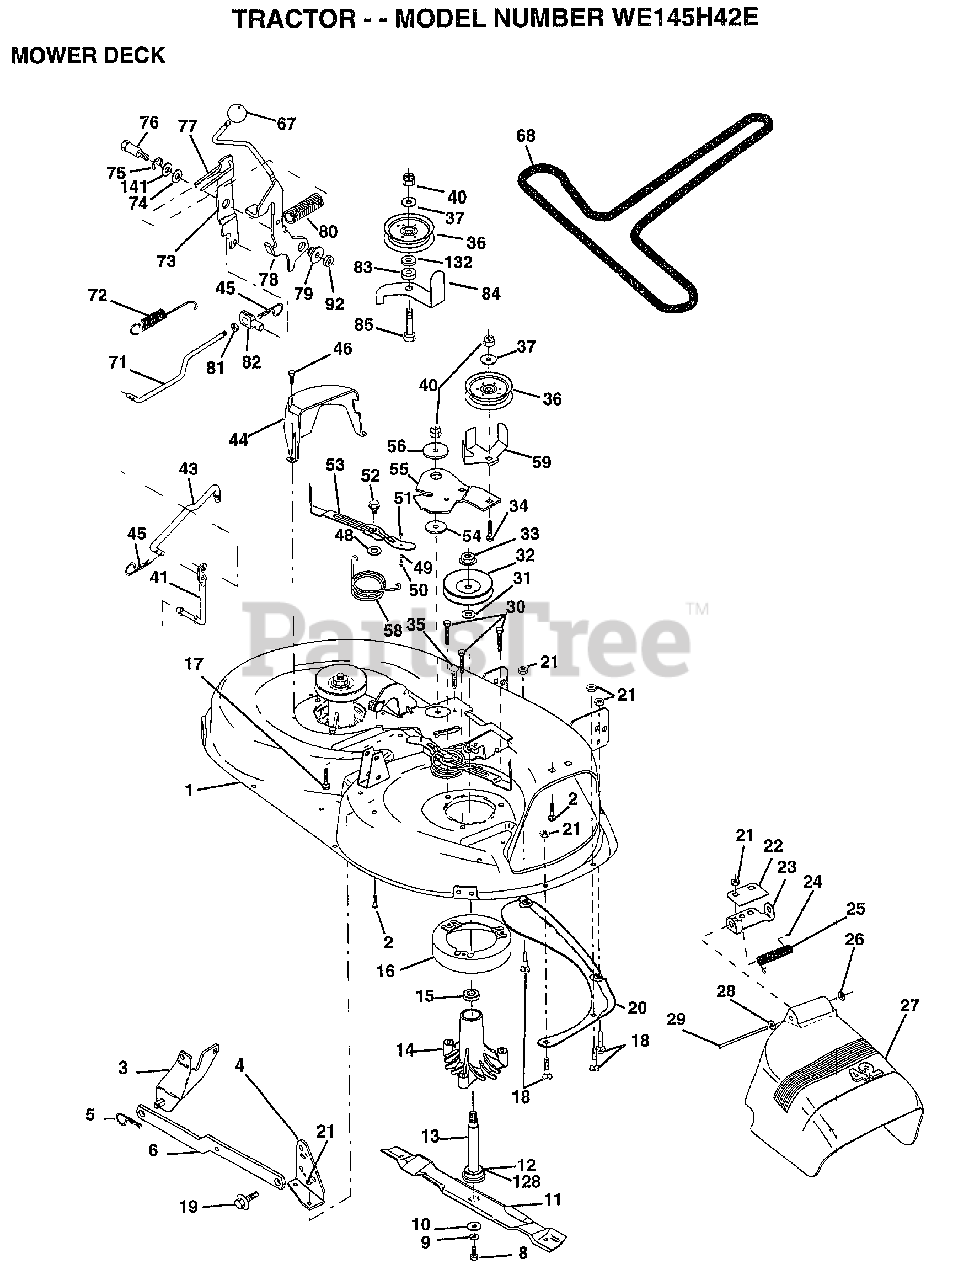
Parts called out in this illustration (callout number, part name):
1	"HOUSING ASSY.42"""
2	BOLT
3	BRKT ASM SWAY BAR
4	BRKT DECK SW BAR
8	BLADE BOLT
10	WASHER.HARD.BLADE
11	"BLADE.42"" HIPERF"
12	BEARING.BALL
14	HSG ASM MANDREL
15	BEARING
16	STRIPPER RND MWR
17	BOLT RDHD 3/8-16
18	BOLT
19	BOLT SHD 5/16-18
20	BAFFLE VORTEX 42
22	STIFFENER BRKT
23	DEFLECTOR BRKT
24	CAP-SLEEVE LT
25	SPRING TORSION
26	NUT PUSH M
27	DEFLECTOR.SHIELD
28	WASHER
29	HINGE ROD
30	"SCREW-THD ROLL,WA"
31	WASHER
32	PULLEY.MANDREL.42
34	BOLT
35	XMAS TREE FASTNER
36	FLAT IDLER PULLEY
37	WASHER
41	PIVOT ROD
43	ROD CLUTCH W/NIBS
44	GUARD MAND LH BLK
45	RETAINER M
46	SCREW.1/4-20X5/8
48	HARD SMALL WASHER
49	ROLLER ASM-CAM
50	SHOULDER BOLT
51	LOCKNUT
52	BOLT.SHLD.5/16-18
53	BRAKE PAD ARM ASM
54	HARDENED WASHER
55	ARM-IDLER
56	SPACER RETAINER
58	SPRING TORSN BRAK
59	GUARD IDLER TUV
67	KNOB.RD.7/16-14
68	BELT.V.T-PATH
71	ROD CLUTCH 38/42
72	RETURN SPRING
73	CLUTCH ARM SECOND
74	WASHER
75	RING
76	SHOULDER BOLT
77	SPRING KEEPER
78	LEVER.ASM.CLUTCH
79	BUSHING
80	SPRING.CLUTCH.MWR
81	NUT
82	TRUNION ADJ
83	WASHER
84	"KEEPER-BELT,FIXED"
85	BOLT
92	NUT
128	WASHER.FELT.
132	WASHER GT
141	WASHER .T
